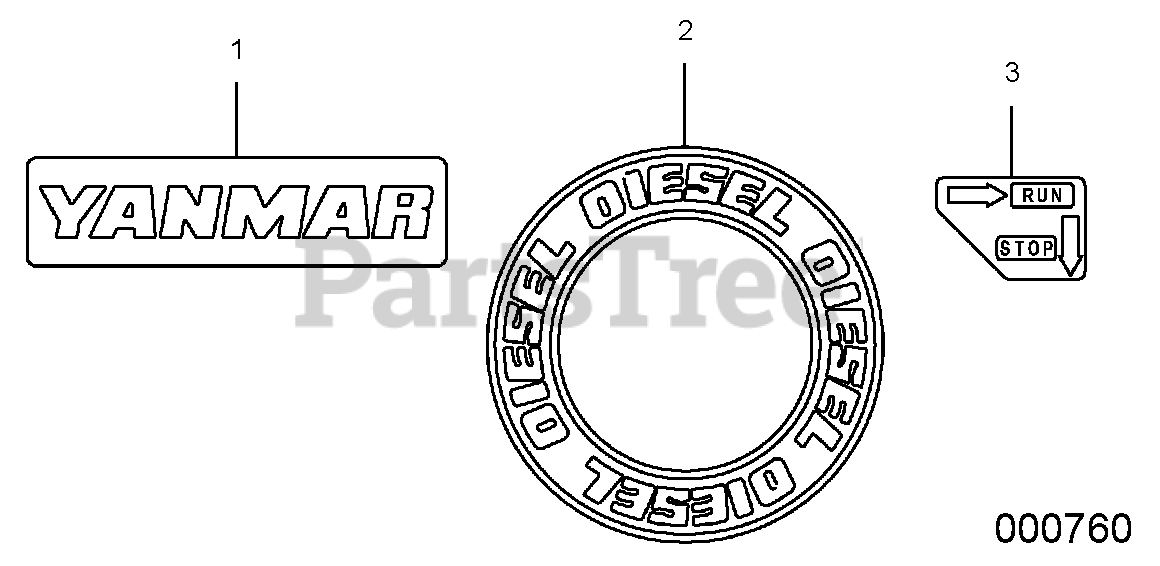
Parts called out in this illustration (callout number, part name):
1	YANMAR MARK B LABEL
2	DIESEL LABEL
3	CONSTANT SPEED LABEL
